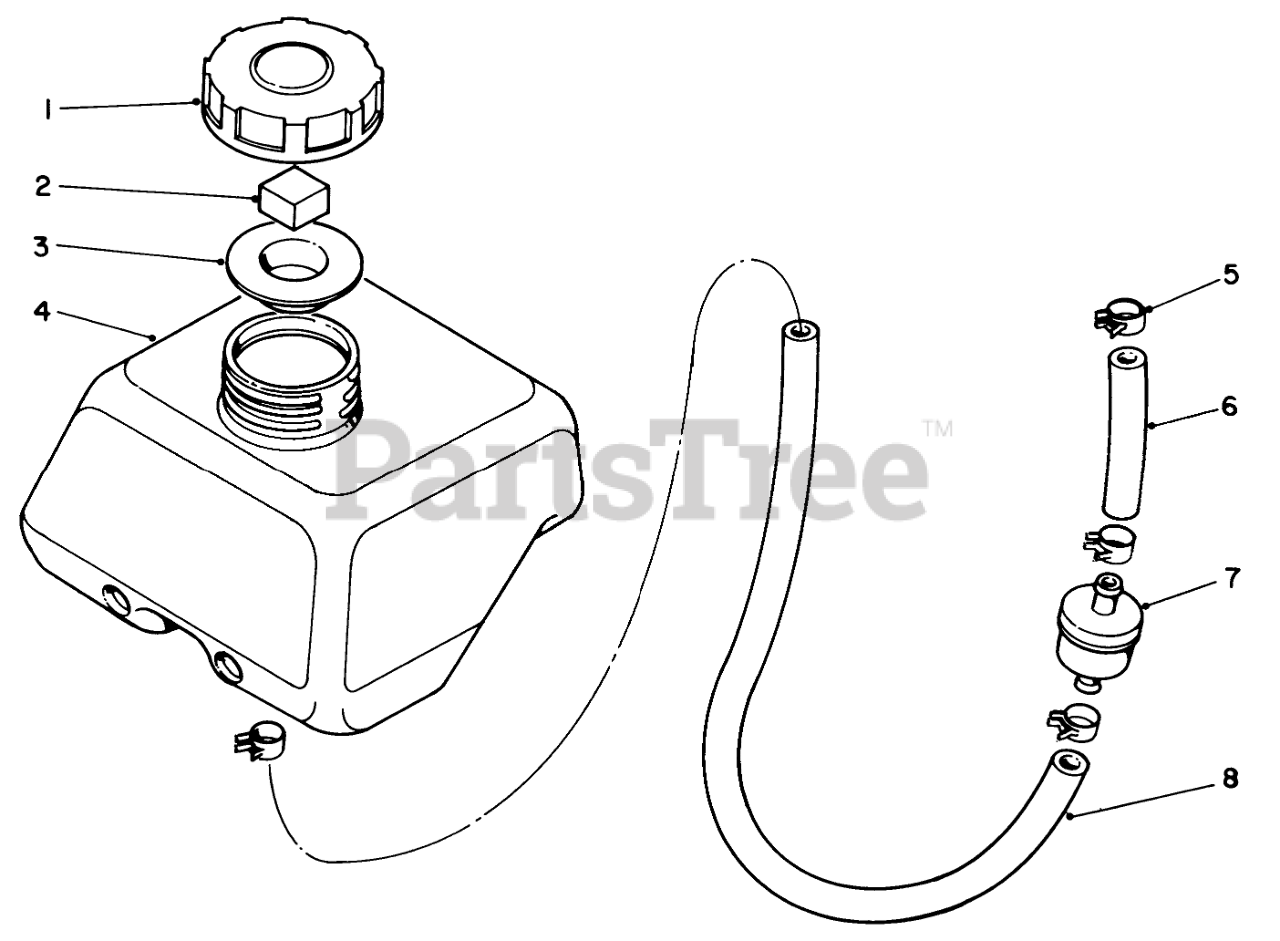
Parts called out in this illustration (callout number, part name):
1	Fuel Cap Assembly (Incl.Ref. #2 & 3)
2	Gasket-Inner
3	Gasket-Outer
4	Tank-Fuel
7	FUEL FILTER
